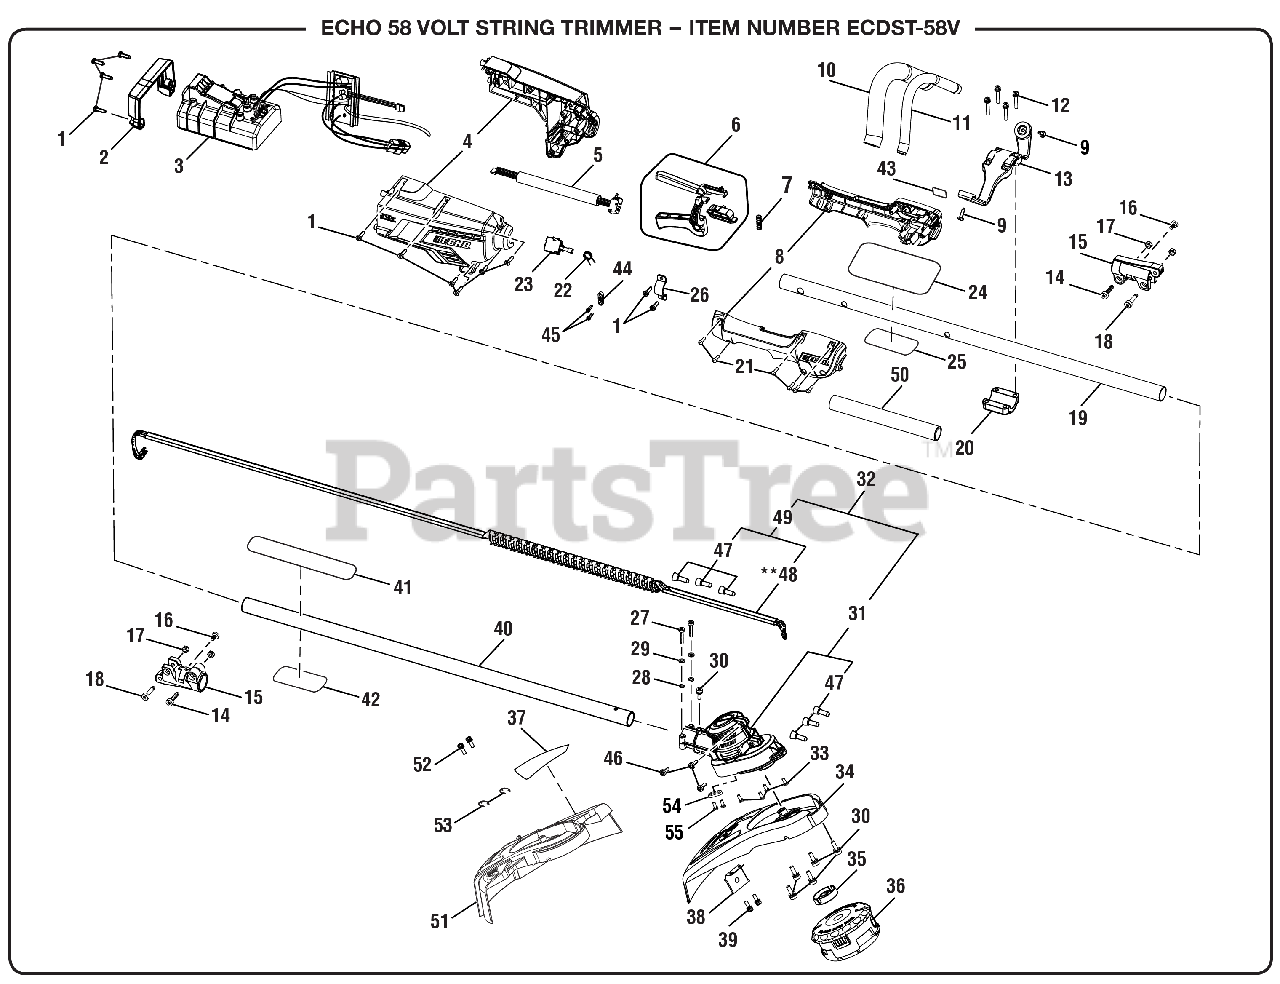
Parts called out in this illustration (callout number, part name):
1	Screw (M5 x 17.5 mm, T20 Torx Pan Hd.)
2	Battery Carriage Fastener
3	Battery Carriage & Motor Controller Assembly
4	Handle Housing Assembly
5	Switch and Wire Assembly
6	Switch Trigger, Lock-Out Button and ON/OFF Switch Assembly
7	Compression Spring (Trigger)
8	Rear Handle Housing Assembly
9	Screw (10-14 x 17 mm, T25 Torx Pan Hd.)
10	Foam Grip
11	Front Handle
12	Screw w/Washers (M5 x 26 mm, Pan Hd.)
13	Handle Bracket
14	Screw (M6 x 25 mm, T25 Torx Pan Hd.)
15	COUPLER
16	Screw (M5 x 10 mm, T25 Torx Pan Hd.)
17	Lock Nut (M6)
18	Screw (M6 x 26 mm, Recessed Hex Soc. Hd.)
19	Upper Boom Assembly (Incl. Key Nos. 24-25)
20	Clamp (Auxiliary Handle)
21	Screw (M4 x 14 mm, T20 Torx Pan Hd.)
22	Torsion Spring
23	Variable Signal Switch
24	Icon Warning Label
25	Data Label
27	Screw (M5 x 26 mm, T25 Torx Pan Hd.)
28	Washer (Special)
29	Washer (ID5.2 x OD10 x 0.8t)
30	Screw w/Washers (M5 x 12.5 mm, T25 Torx Pan Hd.)
31	Motor, Motor Housing and Gear Box Assembly
32	Motor, Motor Housing and Gear Box Assembly
33	Screw (M4 x 9 mm, T20 Torx Pan Hd.)
34	Grass Deflector
36	Stringhead Assembly
37	Warning Label
38	Line Cutting Blade
39	Screw (M4 x 16 mm, Pan Hd.)
40	Lower Boom Assembly (Incl. Key Nos. 41-42)
41	Echo Logo Label (Upper Boom)
42	Icon Warning Label (Lower Boom)
43	Throttle Label
44	Cord Clamp
45	Screw (M4 x 13.5 mm, T15 Torx Pan Hd.)
46	Screw (M4 x 12 mm, T20 Torx Pan Hd.)
47	Wire Connector
48	Main Electric Wire
49	Main Electric Wire
51	Small Guard (Inc. Key No. 54)
52	Screw w/Washers (M5 x 13.5 mm, Pan Hd.)
54	Cord Clamp
55	Cap Screw (M4 x 11 mm, T20 Torx Hd.)
